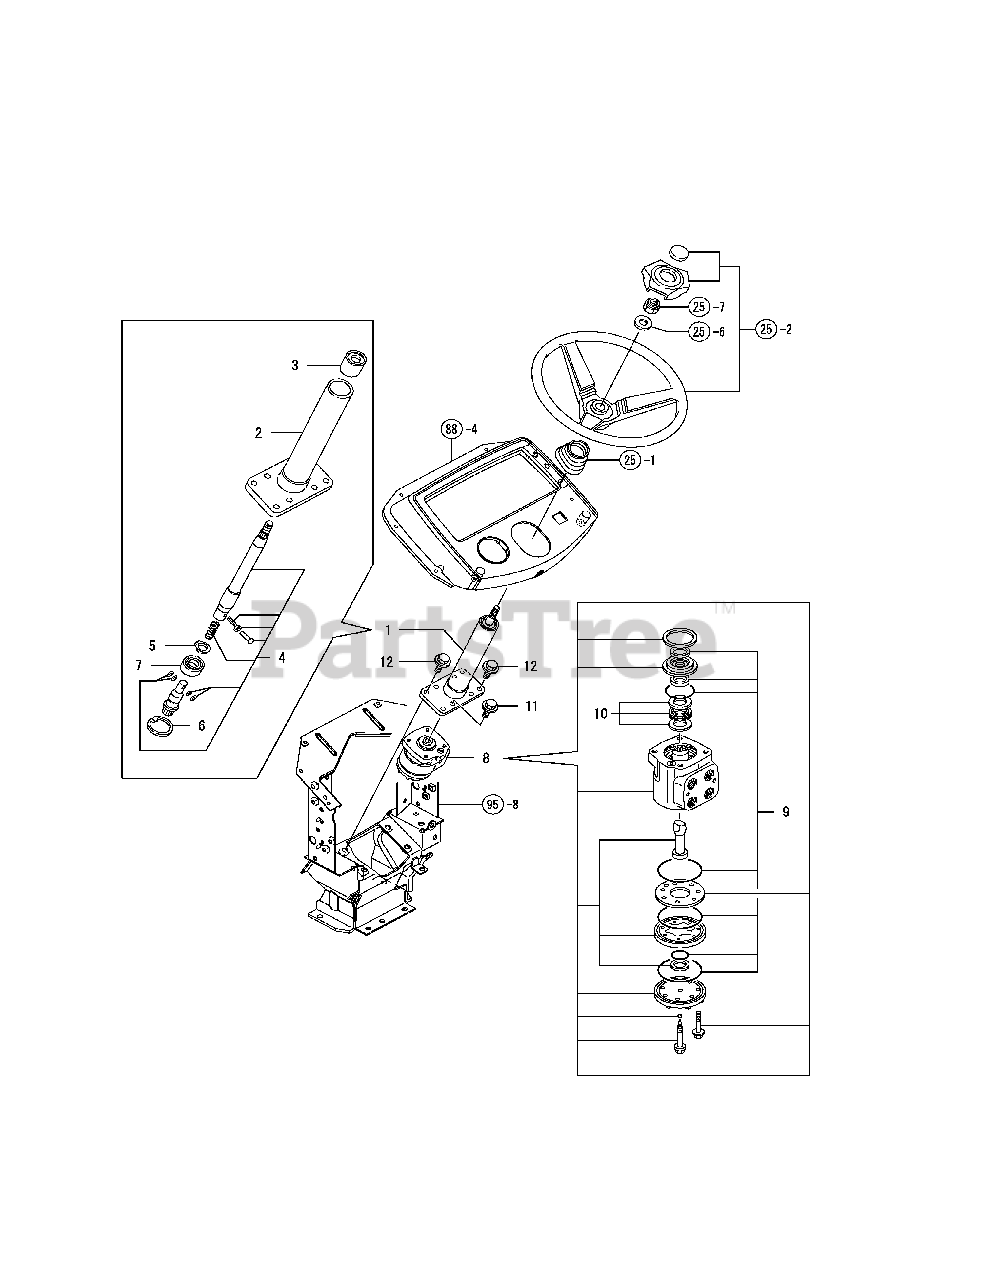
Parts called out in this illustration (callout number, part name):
1	COLUMN, STEERING
8	VALVE ASSY, STEERING
10	BEARING COMP., NEEDLE
11	BOLT M10X 20 PLATED
12	BOLT M10X 20 PLATED
